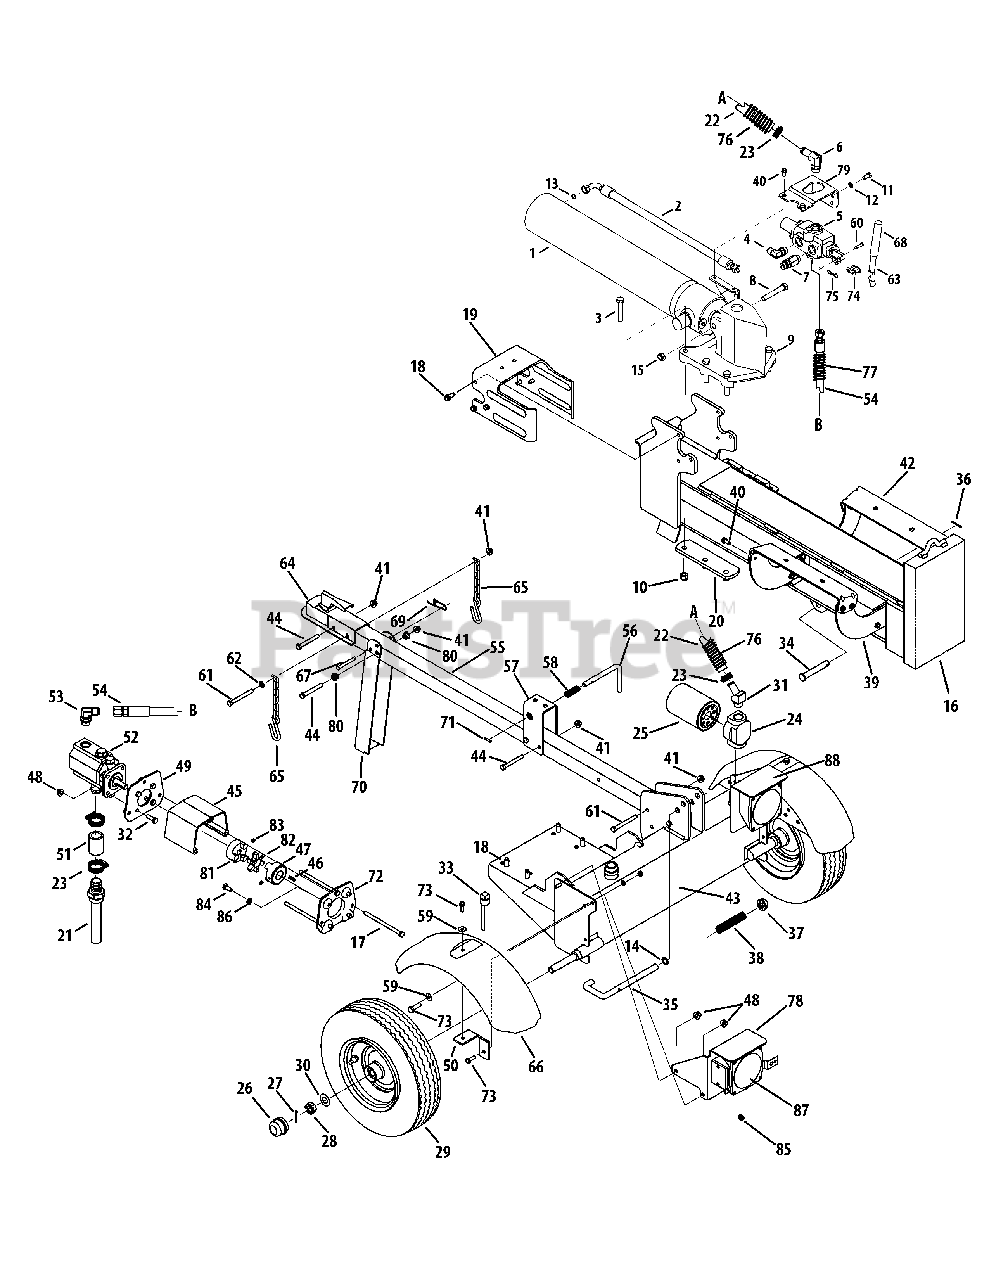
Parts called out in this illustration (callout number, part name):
1	Hydraulic Cylinder
2	Hydraulic Tube
3	Hex Cap Screw, 1/2-20 x 2.75
4	90 Degree Solid Adapter
5	Control Valve
6	Return Elbow
7	Nipple Pipe, 1/2-14
8	Hex Cap Screw, 1/2-13 x 3.25
9	Wedge Assembly
10	Hex Lock Nut, 1/2-20
11	Hex Cap Screw, 3/8-16 x .75
12	Lock Washer, 3/8
13	O-Ring, .489 ID x .070 Dia.
14	Flat Washer, .635 x.93 x.06
15	Hex Lock Nut, 1/2-13
16	Beam Assembly
17	Hex Screw, 5/16-18 x 4.00
18	Self Tapping Screw, 3/8-16 x 1.0
19	Dislodger Bracket
20	Back Plate
21	Inlet Filter
22	Return Hose, 3/4 x 44
23	Hose Clamp, 5/8
24	Filter Housing
25	Oil Filter
26	Hub Cap
27	Cotter Pin
28	Slotted Nut, 3/4-16
29	Complete Wheel Assembly
29	Dust Seal
29	Roller Bearing
30	Flat Washer, .760 x.500
31	Hydraulic Fitting, 1 1/16 Orb x .75
32	Hex Screw, 5/16-18 x 1.00
33	Vented Dipstick
34	Clevis Pin
35	Lock Rod
36	Cotter Pin
37	Push Cap
38	Compression Spring
39	Log Tray Bracket
40	Hex Washer Screw, 5/16-18 x .750
41	Flange Lock Nut, 3/8-16
43	Frame Assembly
44	Hex Bolt, 3/8-16 x 3
45	Coupling Shield
46	Square Key, 3/16" x .75
47	Coupling, .750
48	Flange Lock Nut, 5/16-18
49	Rear Coupling Support Bracket
50	Fender Mounting Bracket
52	Gear Pump
53	45 Degree Elbow Fitting
54	High Pressure Hydraulic Hose
55	Tongue Assembly
56	Latch Rod
58	Compression Spring
59	Flat Washer
60	Clevis Pin
61	Hex Cap Screw, 3/8-16 x 3.50
62	Flat Washer, .375 x.738 x.063
63	Hydraulic Valve Control
64	Hitch Coupling Assembly
66	Fender
67	Clevis Pin
69	Spring Pin
70	Jack Stand
71	Spiral Pin
72	Front Coupling Support Bracket
73	Self-Tapping Screw, 5/16-18 x 1.00
74	Valve Handle Link
75	Cotter Pin, Bow Tie
76	Hose Guard, 48"
77	Hose Guard, 44"
78	RH Light Bracket
79	Outer Valve Bracket
80	Plastic Bushing, .380 ID
81	Coupling, .500
82	Spider Bushing
83	Set Screws
84	Hex Cap Screw, 5/16-24 x .75
85	Jam Nut, 3/8-16
86	Lock Washer, 5/16
87	Light Assembly Kit
88	LH Light Bracket
